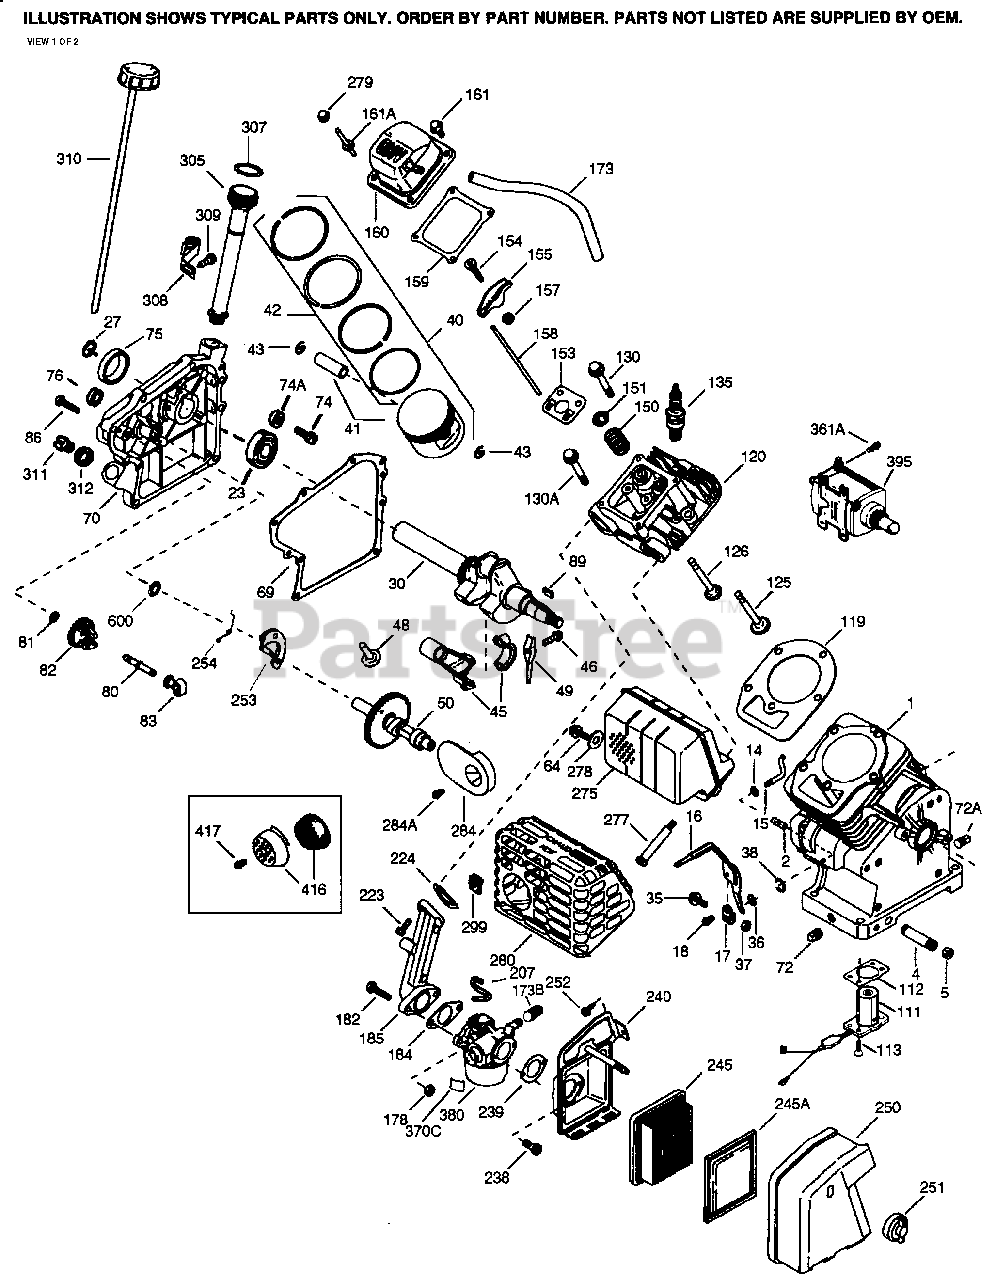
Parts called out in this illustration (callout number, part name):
1	"Cylinder (Incl. 2, 20 & 72)
2	Dowel Pin
14	Flat Washer
15	Governor Rod
16	Governor Lever
17	Governor Lever Clamp
18	Screw, Torx T-15, 8-32 x 3/8"
23	Ball Bearing
27	Bearing Retainer
30	Crankshaft
35	Screw, 10-32 x 3/4"
36	Lock Washer #8
37	Lock Nut, 10-32
38	Retaining Ring
40	Piston, Pin & Ring Set (Std.)
40	Piston, Pin & Ring Set (.010" OS)
41	Piston & Pin Ass'y. (Std.) (Incl. 43)
41	Piston & Pin Ass'y. (.010" OS) Incl. 43
42	Ring Set (Std.)
42	Ring Set (.010" OS)
43	Piston Pin Retaining Ring
45	Connecting Rod Ass'y. (Incl. 46 & 49)
46	Connecting Rod Bolt
48	Valve Lifter
49	Oil Dipper
50	Camshaft (Incl. 253 & 254)
64	Screw, 1/4-20 x 1-1/8"
69	* Cylinder Cover Gasket
70	Cylinder Cover Incl. 75 thru 83 & 311
72	Oil Drain Plug (Sq. hd., 1/4-18)
74	Screw, 10-24 x 9/16"
75	Oil Seal
80	Governor Shaft
82	Governor Gear Ass'y. (Incl. 81)
83	Governor Spool
86	Screw, 1/4-20 x 1-1/4"
89	Flywheel Key (also available in Packa ged Part #740007B)
119	* Cylinder Head Gasket
120	Cylinder Head
125	Exhaust Valve (Std.) (Incl. 151)
125	Exhaust Valve (1/32" OS) (Incl. 151)
126	Exhaust Valve (1/32" OS) (Incl. 151)
126	Intake Valve (Std.) (Incl. 151 & 151A )
130	Screw, 5/16-18 x 1-1/2"
130A	Screw, 5/16-18 x 2-41/64"
135	Resistor Spark Plug (RN4C) also avail able in Packaged Part #740069
150	Valve Spring
151	Valve Spring Cap
153	Push Rod Guide
154	Rocker Arm Stud
155	Rocker Arm
157	Nut, 1/4-28
158	Push Rod
159	* Rocker Arm Cover Gasket
160	Rocker Arm Cover
161	Screw, 1/4-20 x 31/64"
173	Breather Tube
178	Nut, 1/4-20
182	Screw, 1/4-20 x 1"
184	* Carburetor To Intake Pipe Gasket
185	Intake Pipe
207	Throttle Link
223	Screw, 1/4-20 x 1"
224	* Intake Pipe Gasket
238	Screw, 10-32 x 1/2"
239	* Air Cleaner Gasket
240	Air Cleaner Body (Incl. 239)
245	Air Filter (Paper) (also available in Packaged Part #740031B for model VLV only) (also available in Packaged Pa rt #740061C for model OH195)
245A	Poly Pre-Filter (also available in Pa ckaged Part #740061C)
250	Air Cleaner Cover
251	Wing Nut
252	Screw, 10-32 x 1/2"
253	Compression Release Weight
254	Compression Release Spring
275	Muffler
277	Screw, 1/4-20 x 2-9/32"
279	Nut & Lock Washer
280	Heat Shield
310	Dipstick
311	Oil Fill Plug (Incl. 312) also availa ble in Packaged Part #740079
380	Carburetor (Incl. 184)
416	Spark Arrestor Kit (Incl. 417)
417	Screw, 8-32 x 3/8"
999	Summer Maintenance Kit (incl. Oil, Sp ark Plug, Air Cleaner, & Ultra Fresh)
